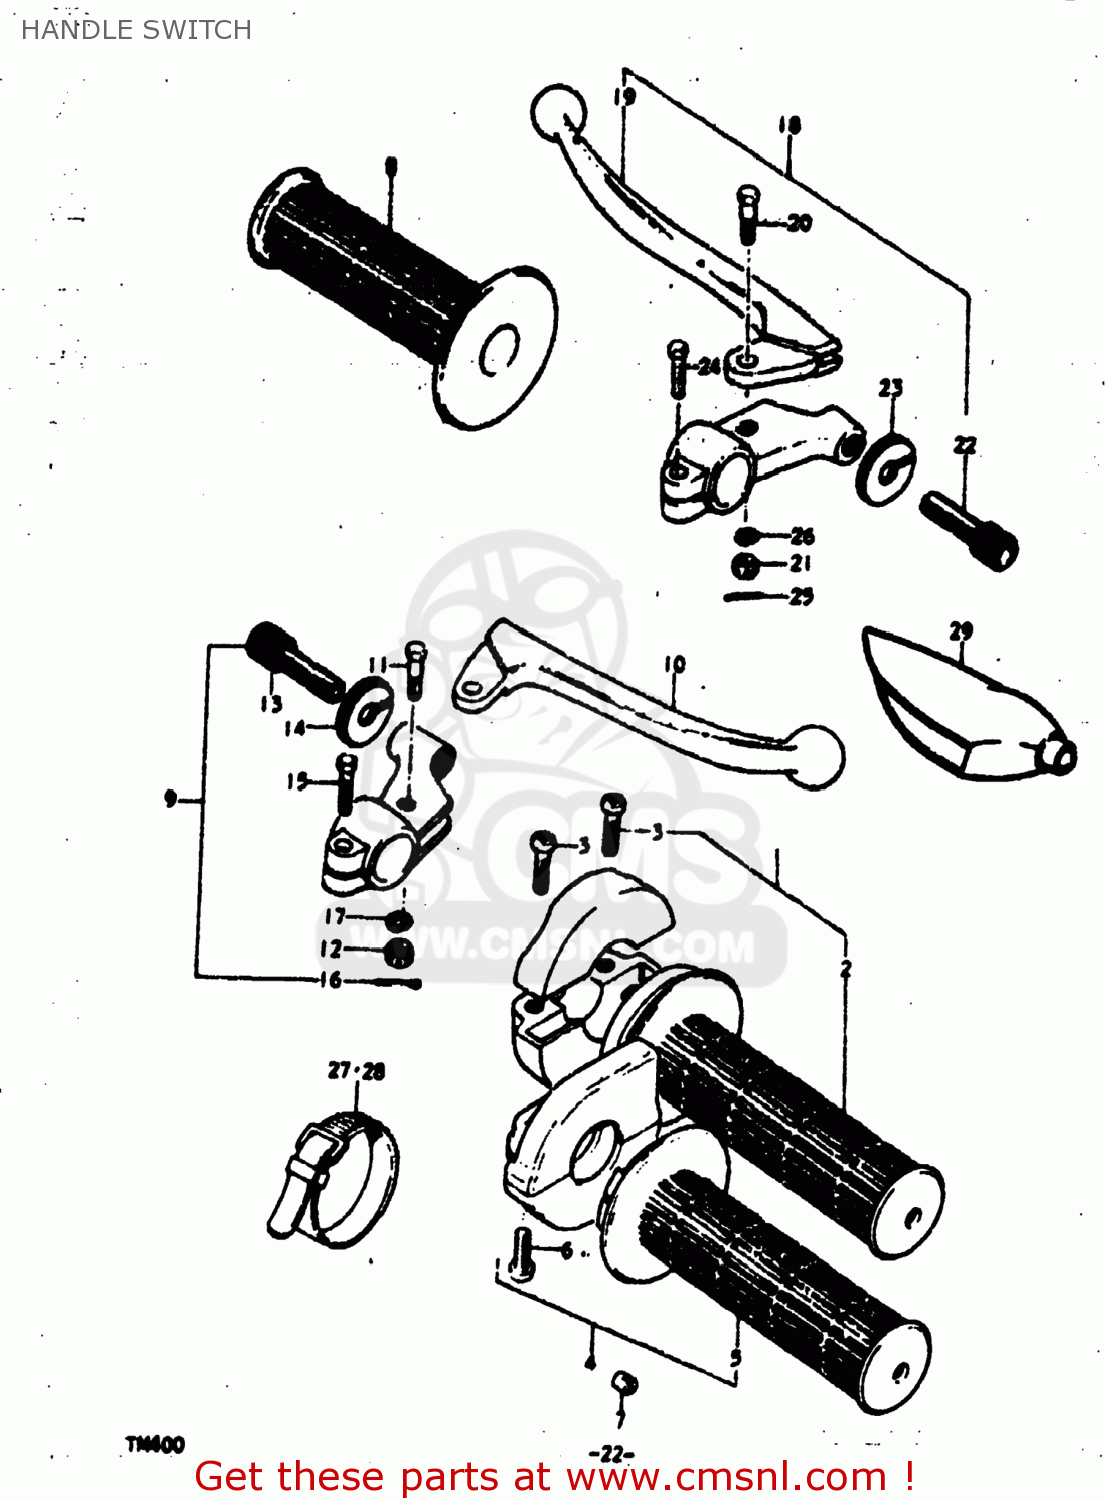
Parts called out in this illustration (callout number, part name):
1	CASE ASSEMBLY,THROTTLE
2	GRIP,THROTTLE
3	SCREW
4	CASE ASSEMBLY,THROTTLE
5	GRIP,THROTTLE
6	SCREW
7	PIECE,THROTTLE END
8	GRIP,LEFT
9	LEVER ASSEMBLY,BRAKE
10	LEVER,BRAKE
11	BOLT,LEVER
12	NUT,LEVER FITTNG
13	ADJUSTER,CABLE
14	NUT,CABLE ADJUSTER
15	BOLT
16	COTTER PIN
17	LOCK WASHER
18	LEVER ASSEMBLY
19	LEVER,CLUTCH
20	LEVER HOLDER FITTING BOLT
21	NUT,LEVER FITTNG
22	ADJUSTER,CABLE
23	NUT,CABLE ADJUSTER
24	BOLT
25	COTTER PIN
26	LOCK WASHER
27	CLAMP(L:120)
28	CLAMP
29	COVER,CLUTCH LEVER
